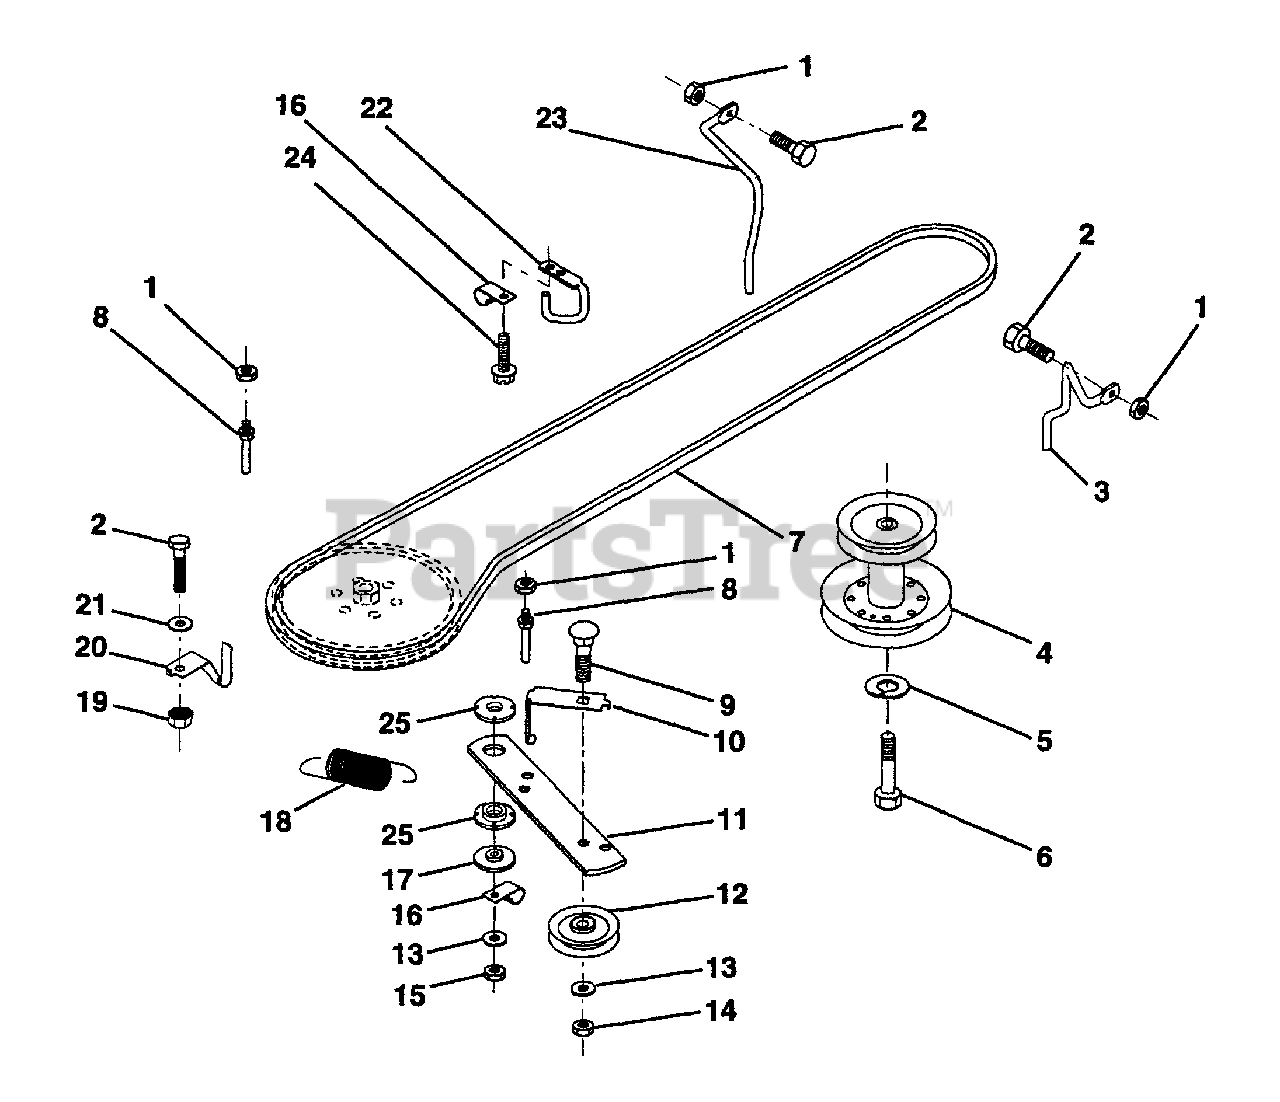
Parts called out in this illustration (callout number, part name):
1	Nut, Crownlock 5/16-18
2	Bolt, Hex Head 5/16-18 UNC x 3/4
3	Keeper, Mower Drive, R.H.
4	Pulley, Engine
5	Washer, Lock 7/16
6	Bolt, Hex Hd. 7/16-20 UNF Grade 5
7	Traction, V-Belt Drive
8	Keeper, T/A, Ground Drive Belt
9	Bolt, Carriage 3/8-16 UNC x 1-1/2
10	Keeper, Ground Drive Belt Idler
11	Arm, Ground Drive Clutch
12	Idler, Flat
13	Washer 13/32 x 13/16 x 16 Gauge
14	Nut, Hex, Centerlock 3/8-16 UNC
15	Nut, Hex, Crownlock 3/8-16 UNC
17	Spacer, Retainer
18	Spring, Extension
19	Nut, Hex, Keps 5/16-18 UNC
20	Keeper, T/A, Ground Drive Belt
21	Washer 11/32 x 5/8 x 16 Gauge
22	Keeper, Frame Ground Drive Belt
23	Keeper, Belt LH
24	Screw, THD Cut
25	Bushing Nylon
35	Clip Insulated
